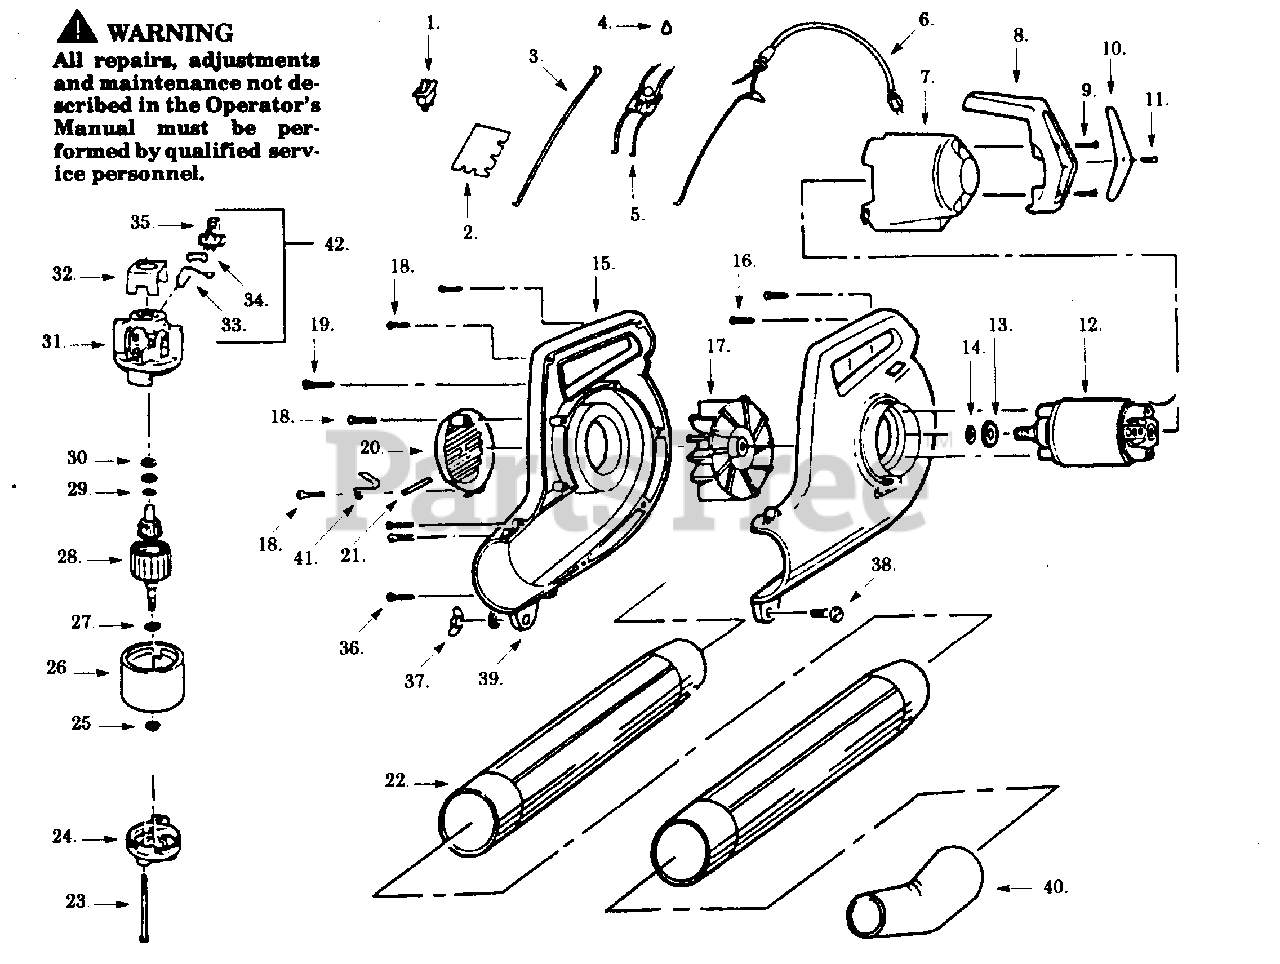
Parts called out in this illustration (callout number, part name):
1	On-Off Switch
2	Mounting Board
3	Lead Wire Ass'y.
4	Connector
5	P.C. Board Ass'y.
6	Power Cord Ass'y.
7	Motor Cover
14	Retaining Ring
15	R.H./L.H. Housing
17	Impeller Ass'y.
20	Inlet Cover
21	Hinge Pin
22	Outlet Tube
24	Endbell Output
26	Field Ass'y.
27	Retainer Ring
28	Armature
29	Retainer Ring
31	Endbell (Brush)
32	Insulator
34	Brush Spring
35	Brush Holder
37	Wing Nut
40	Curved Nozzle
42	Brush Kit (Incl. 33,34,35)
